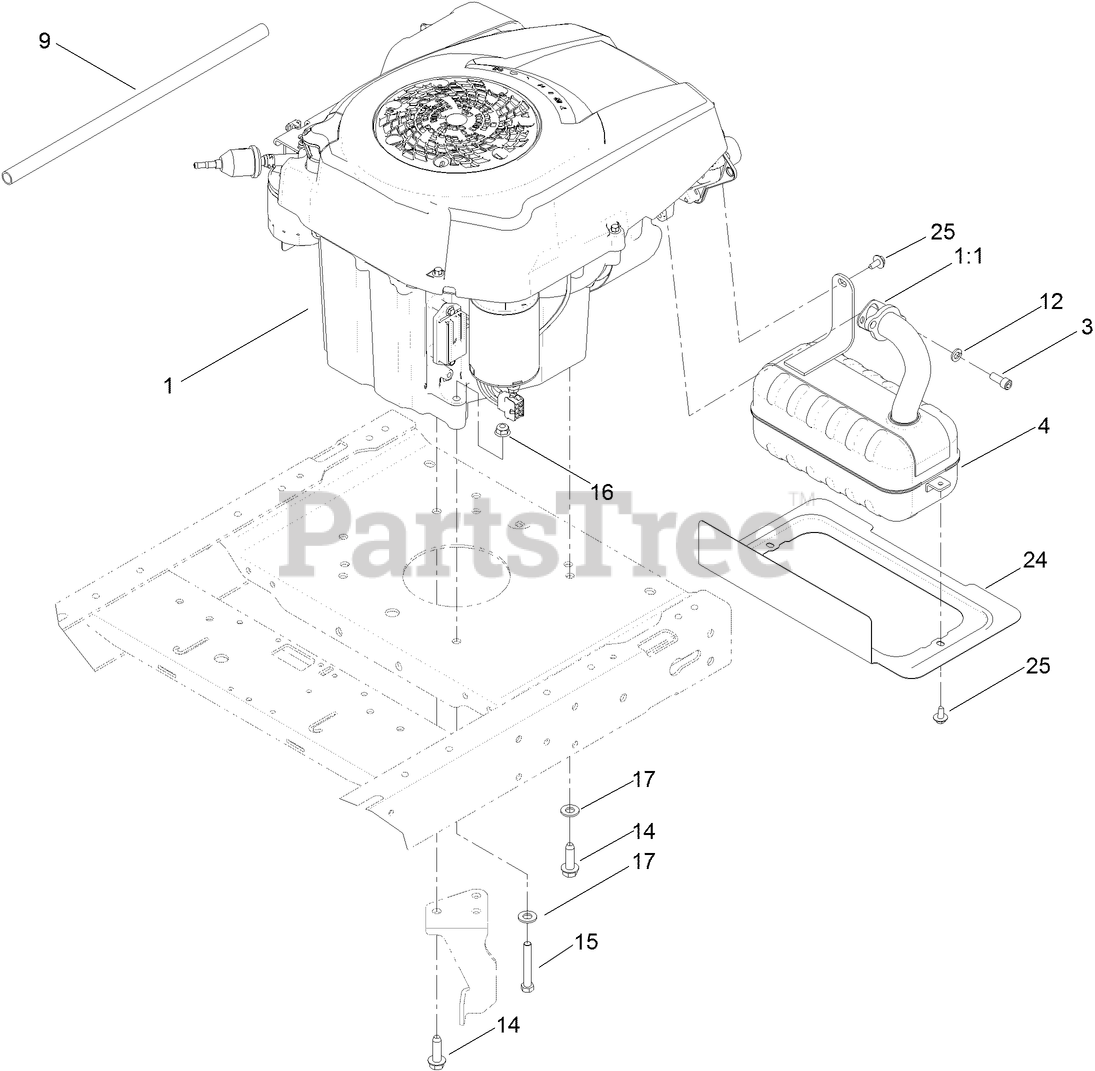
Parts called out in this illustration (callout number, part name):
1:1	GASKET-EXHAUST
3	SCREW-HSH
4	MUFFLER-KOHLER
9	TUBE-DRAIN, OIL
12	WASHER-LOCK
14	SCREW-THD
15	SCREW-HH
16	NUT-HF, NI
17	WASHER-FLAT
24	SHIELD-HEAT
25	SCREW-HHFTF
